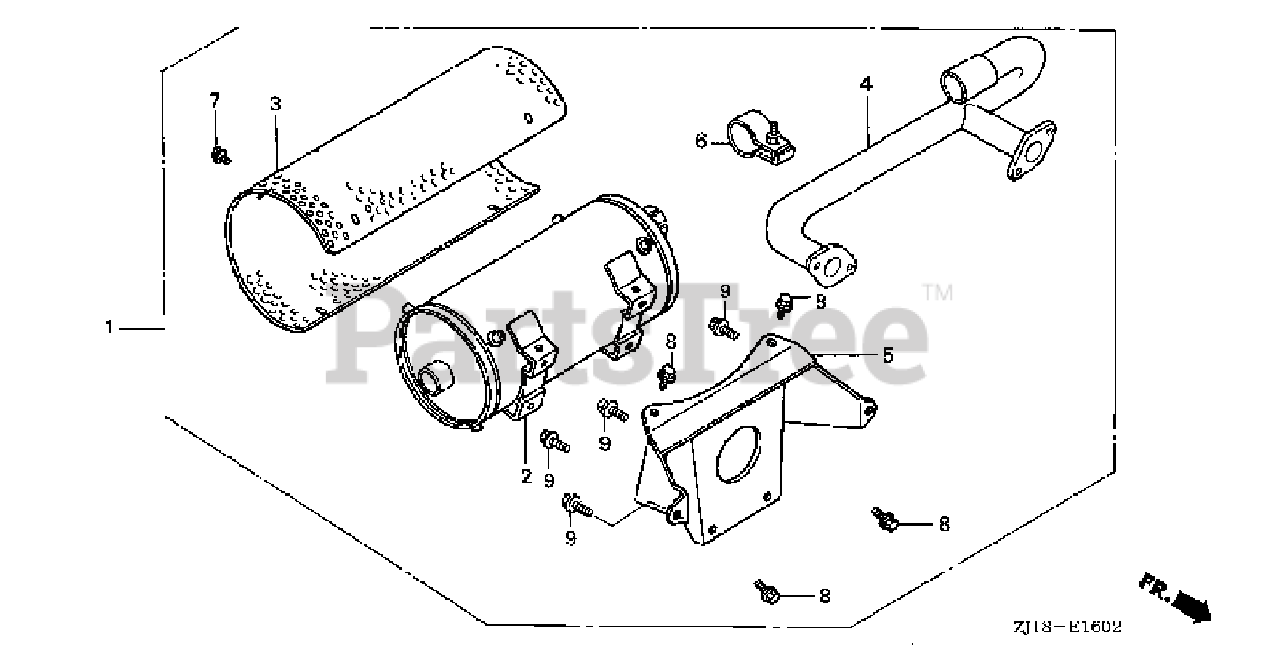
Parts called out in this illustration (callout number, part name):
1	MUFFLER KIT (HIGH-B) (N/A: SEE COMPONENTS)
2	MUFFLER (HIGH)
3	PROTECTOR, MUFFLER (HIGH)
4	PIPE, EX. (HIGH-L)
5	STAY, MUFFLER (HIGH)
6	BAND ASSY.
7	BOLT, FLANGE (6X8)
8	BOLT, FLANGE (8X14)
9	BOLT, FLANGE (8X20)
